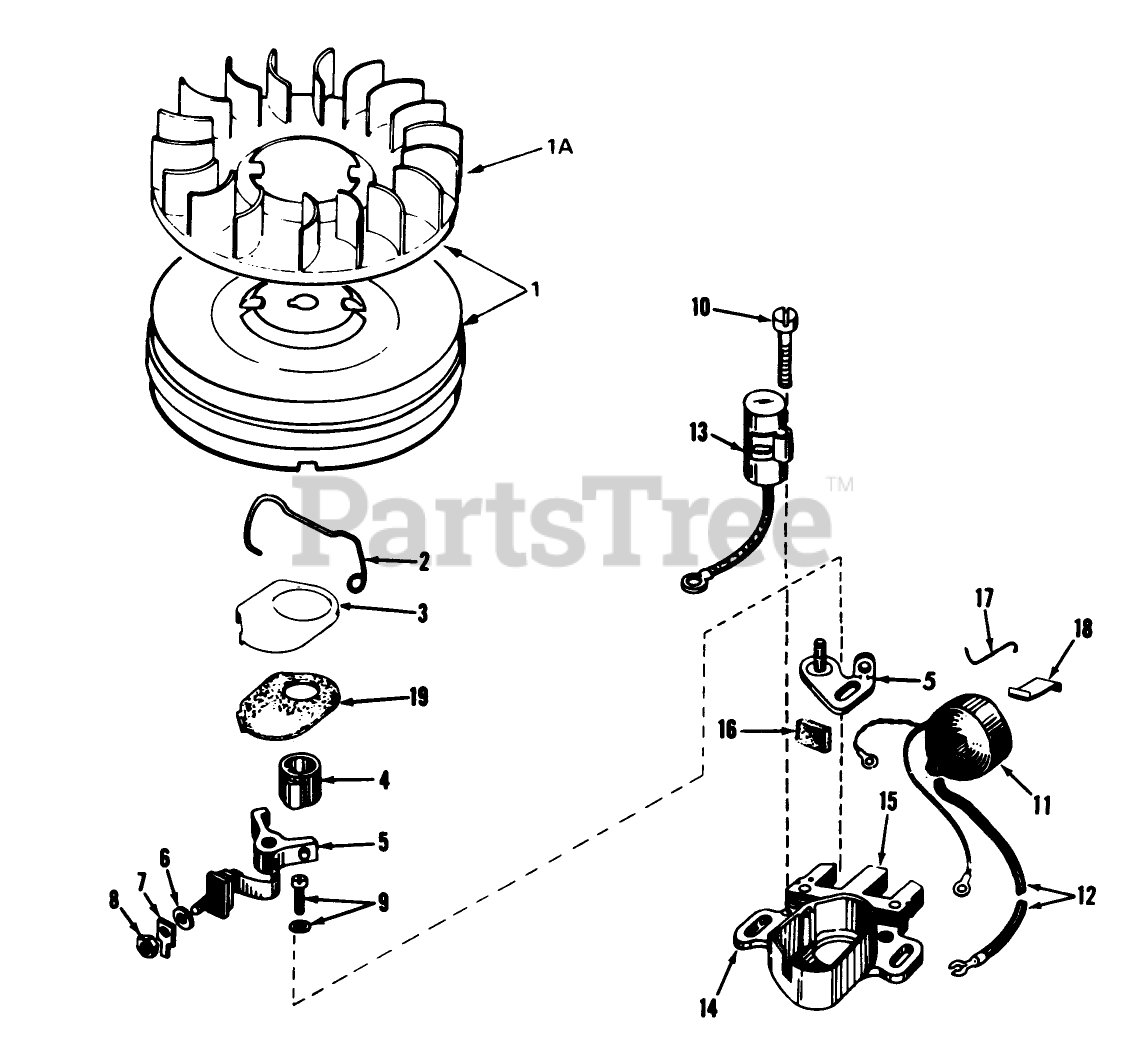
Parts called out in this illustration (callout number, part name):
1	Flywheel (Incl. No. 1A)
2	Spring Breaker Box
3	Cover-Dust
4	Cam-Breaker
5	Breaker Assy.
6	Washer
7	Terminal, Ground
8	DECAL
9	Breaker Screw
10	Condenser Screw
11	Coil Assy. (Incl. No. 12)
12	Wire, Lead
13	Condenser
14	Core Plate
15	Stator Assy. (Incl. Ref. #2 thru 11, 13, 14, 16, 17 19)
16	Felt,Cam Wiper
17	Clip, Coil
18	Spring Coil Wedge
19	Gasket-Dust Cover
19	Gasket, Dust Cover
